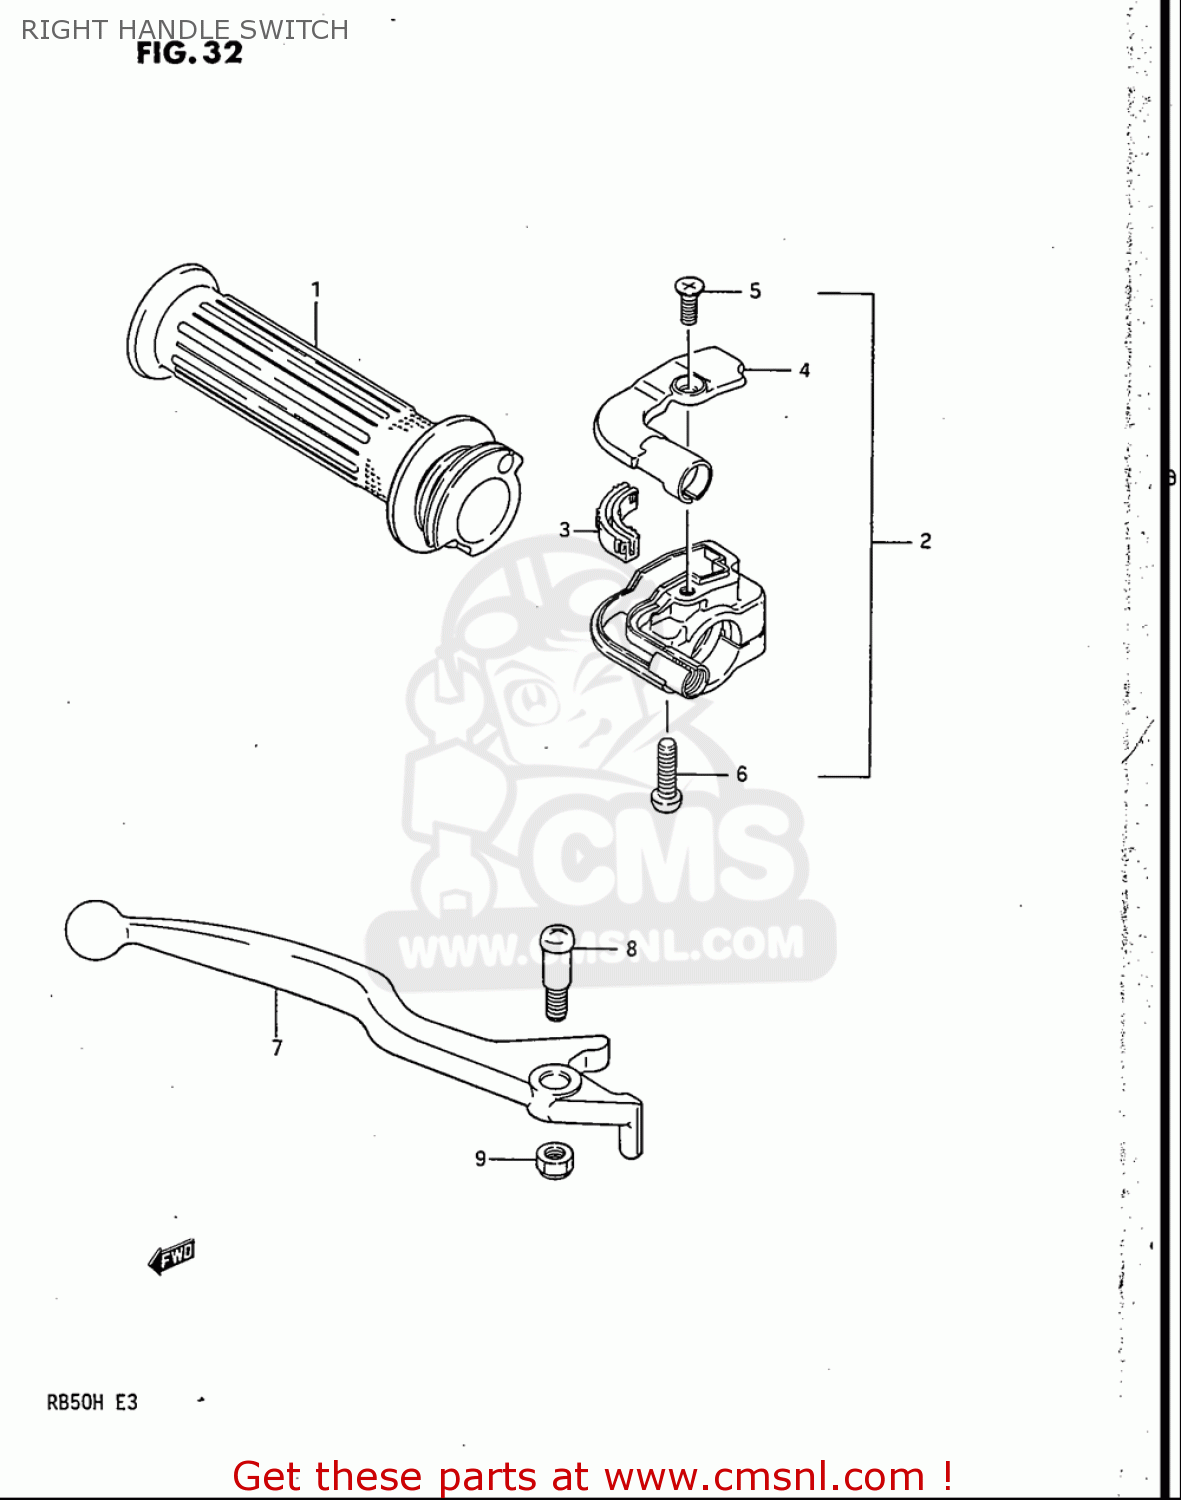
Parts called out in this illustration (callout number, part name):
1	GRIP,THROTTLE
2	CASE ASSEMBLY,THROTTLE
3	GUIDE PIECE,THROTTLE
4	COVER,THROTTLE CASE
5	SCREW
6	SCREW
7	LEVER,BRAKE
8	SCREW
9	NUT
